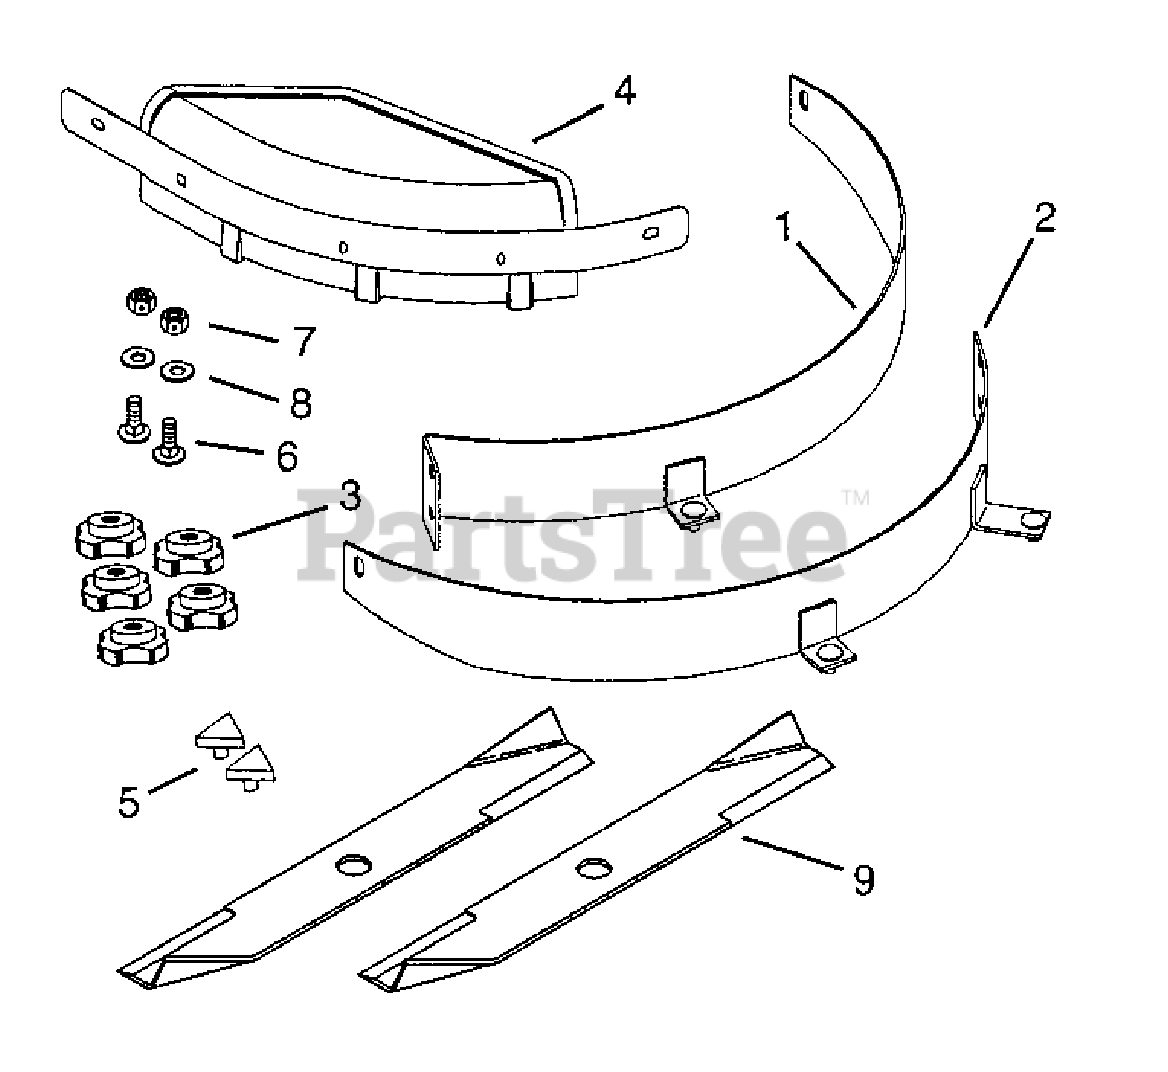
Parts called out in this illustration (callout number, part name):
1	Weldment, Mulch Baffle RH
2	Weldment, Mulch Baffle LH
3	Knob
4	Mulch Cover
6	Bolt, Rnd Hd Sq Nk .31-18 x .75
7	Nut, Lk Cntr .31-18
8	Washer, Flat Stl.
9	Blade, Mulch 22"
